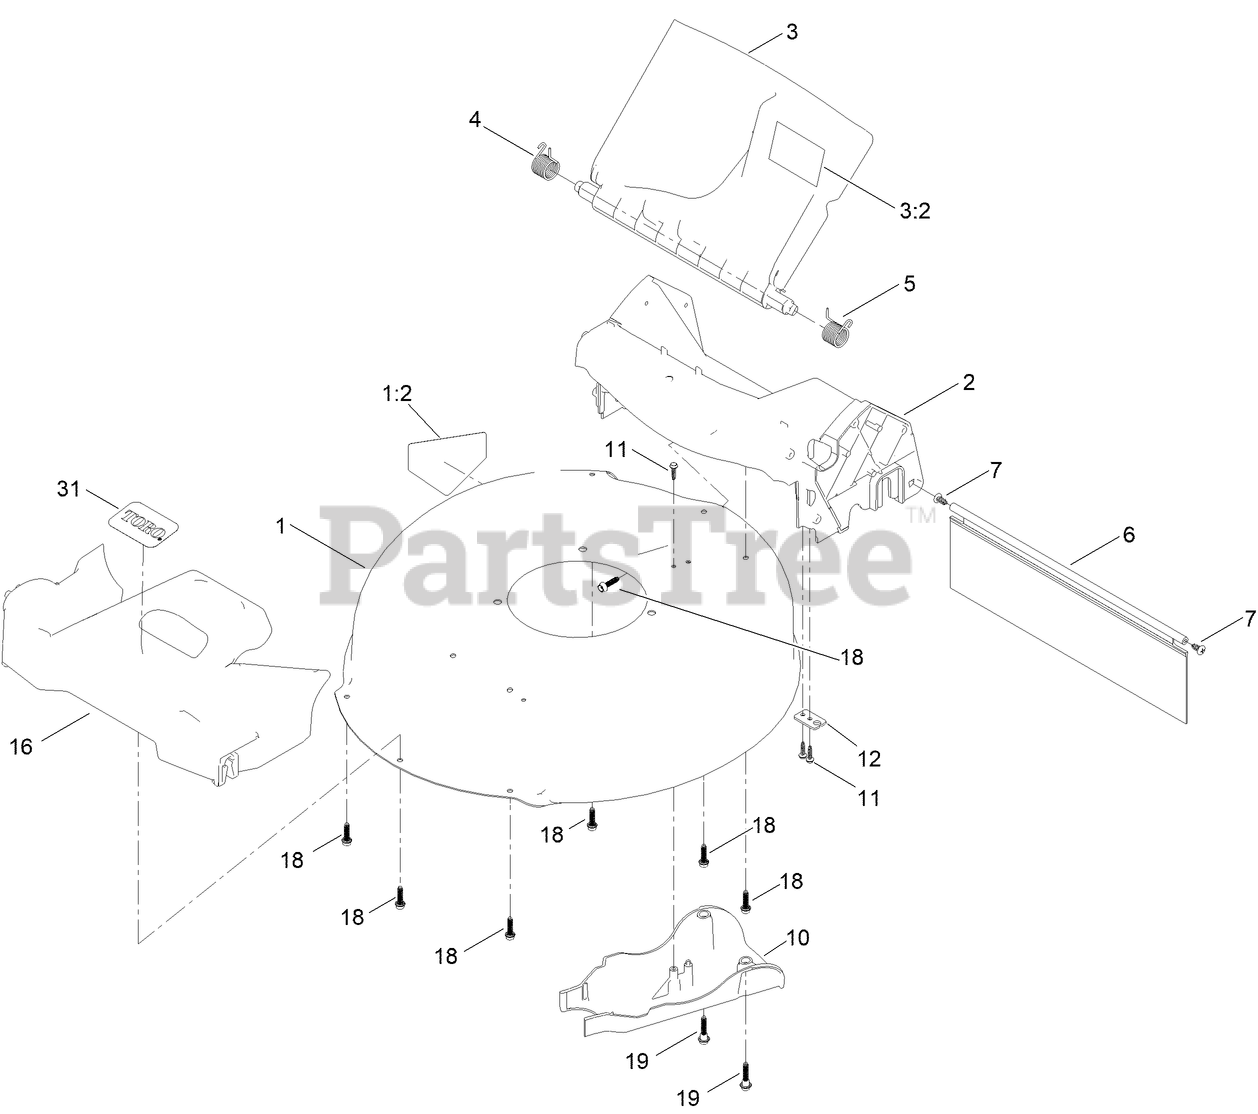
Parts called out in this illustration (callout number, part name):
1	HOUSING ASM
1:2	DECAL-DANGER
2	CHUTE-SP/AWD, 21 IN
3	DEFLECTOR-REAR ASM
3:2	DECAL-WARNING
4	SPRING-TORSION
5	SPRING-TORSION
6	SHIELD-TRAILING
7	SCREW-PTH
10	COVER-BELT
11	SCREW-HWH
12	BRACKET-CABLE
16	BUMPER
18	SCREW-FLANGE, PLASTIC
19	SCREW-SHOULDER, HHF
31	DECAL-TORO, SILVER
